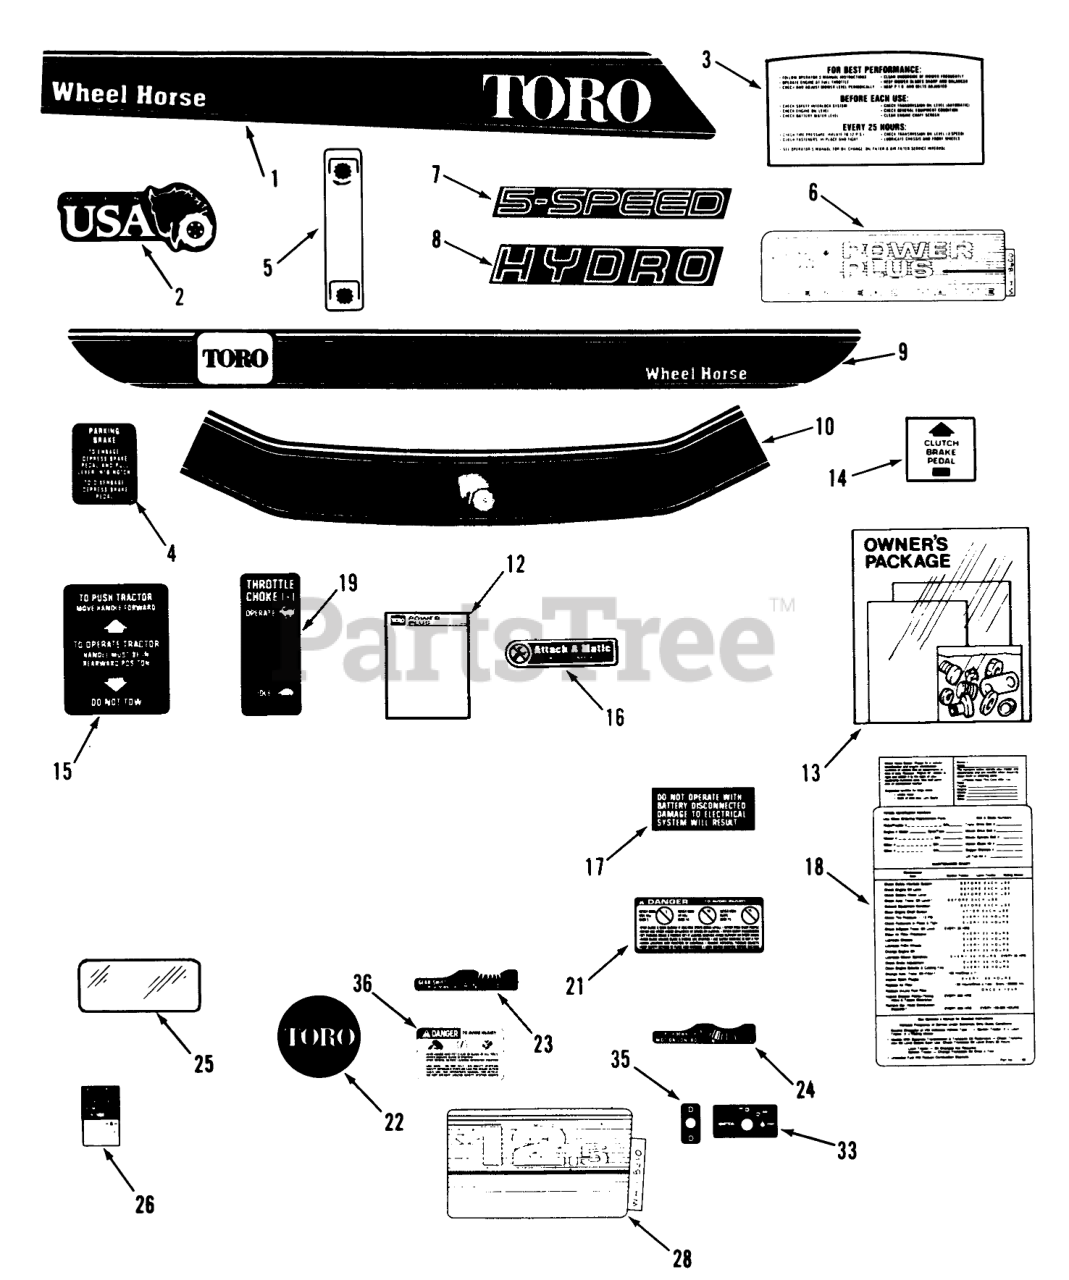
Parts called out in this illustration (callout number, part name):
1	DECAL-HOOD 210-5 R H
3	Decal-Hood Rear
4	DECAL PARKING BRAKE
5	DECAL-PTO
6	DECAL-PWR PLUS
7	DECAL-MODEL 5-SPEED
8	DECAL-MODEL HYDRO
9	DECAL-FENDER
10	DECAL-FRONT HOOD
13	Loose Parts Package (210-5)
14	DECAL CLUTCH & BRAKE
15	DECAL-PUSH
16	Decal-Attach-A-Matic
17	DECAL ELECT SYSTEM
18	MAINTENANCE-DECAL
19	DECAL-THROTTLE
21	DECAL-DANGER
22	DECAL-TORO ENGINE
23	DECAL-SHIFT 5-SPEED
24	DECAL-MOTION CONTROL
26	DECAL-PTO BELT ADJ
28	DECAL-PWR PLUS 12.5
33	DECAL-IGNITION
35	DECAL-LIGHTS
36	DECAL-DANGER
